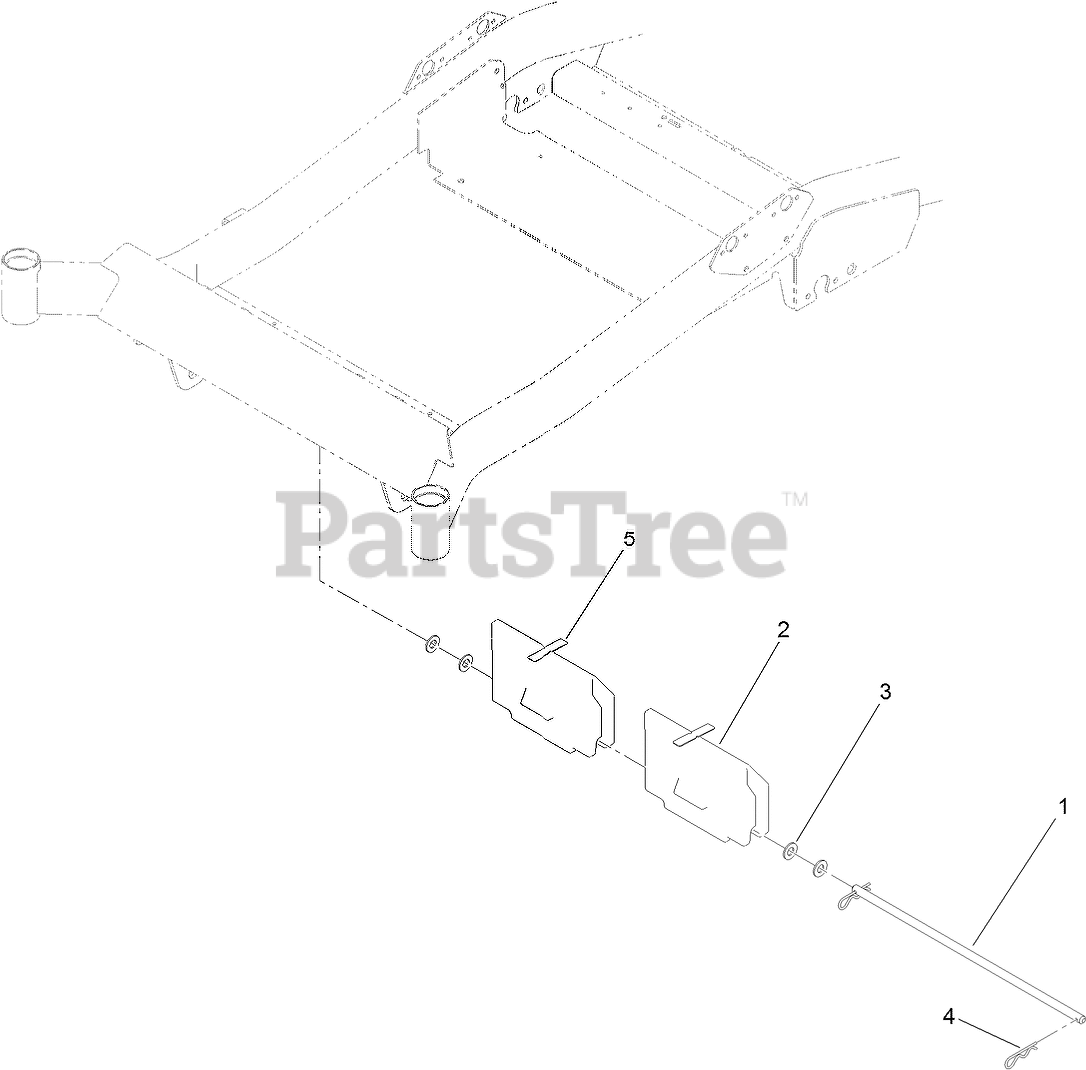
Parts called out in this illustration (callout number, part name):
1	ROD-DECK, PIVOT
2	WEIGHT-BAGGER
3	WASHER-FLAT
4	PIN-HAIR
5	BUMPER-PAD
